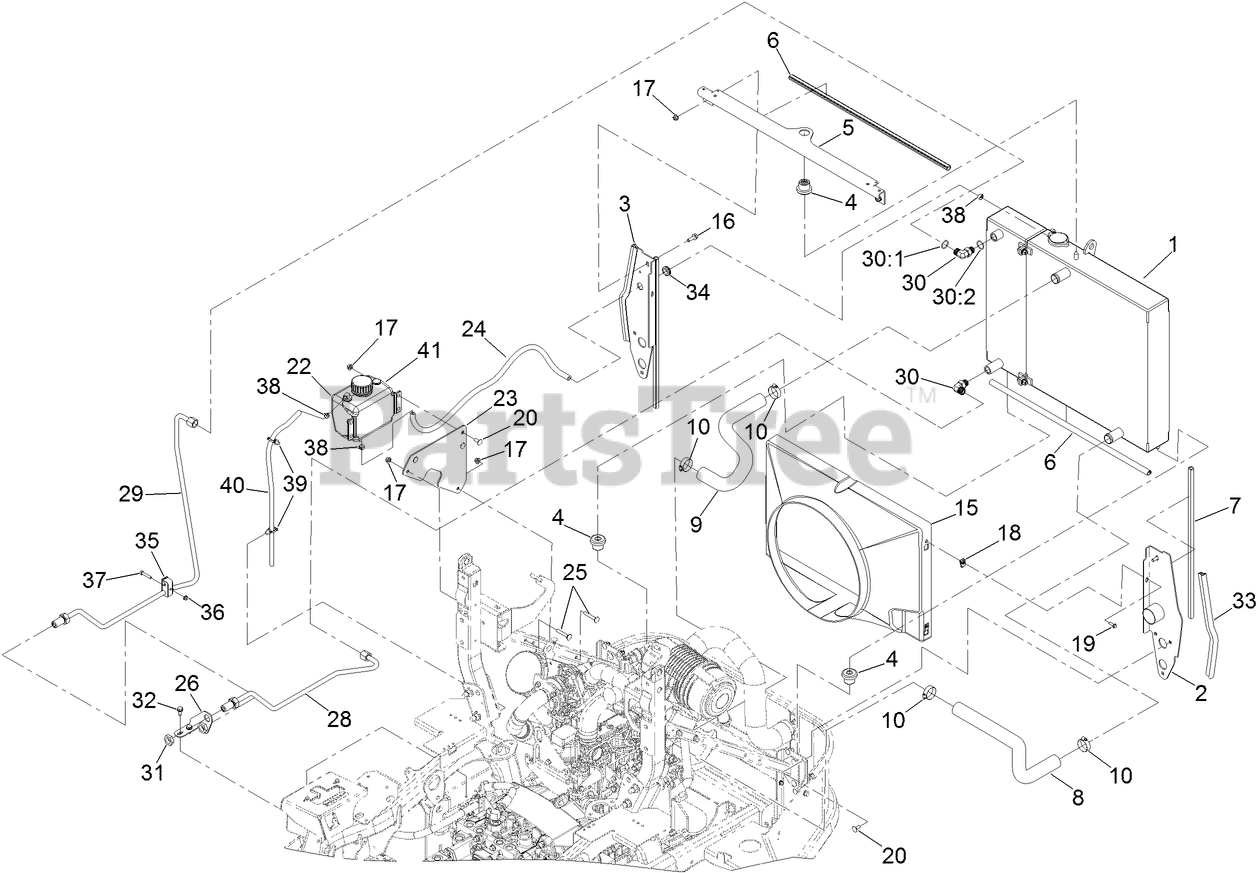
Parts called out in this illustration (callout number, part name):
1	COOLING ASM
2	SUPPORT-RADIATOR, LH
3	SUPPORT-RADIATOR, RH
4	MOUNT-ISOLATOR
5	BRACKET-COOLING, TOP
6	SEAL-BULB
7	SEAL-BULB
8	HOSE-RADIATOR, LOWER
9	HOSE-RADIATOR, UPPER
10	CLAMP-HOSE
15	SHROUD-FAN
16	SCREW-HHF
17	NUT-HF, NI
19	SCREW-HWH
20	SCREW-CARR
22	TANK-OVERFLOW, W/CAP
23	BRACKET-BOTTLE
24	HOSE-FUEL
25	BOLT-CARR
26	BRACKET-BULKHEAD
28	HYDRAULIC TUBE ASM
29	HYDRAULIC TUBE ASM
30	FITTING-ELBOW, 90 DEG
30:1	O-RING
30:2	O-RING
31	NUT-BULKHEAD
32	SCREW-HWHTF
33	SEAL-BULB
34	GROMMET
35	CLAMP-TWIN
36	NUT-HF
37	SCREW-HH
38	CLAMP-HOSE
39	CLIP-TIE
40	HOSE-FUEL
41	CAP-W/TETHER
